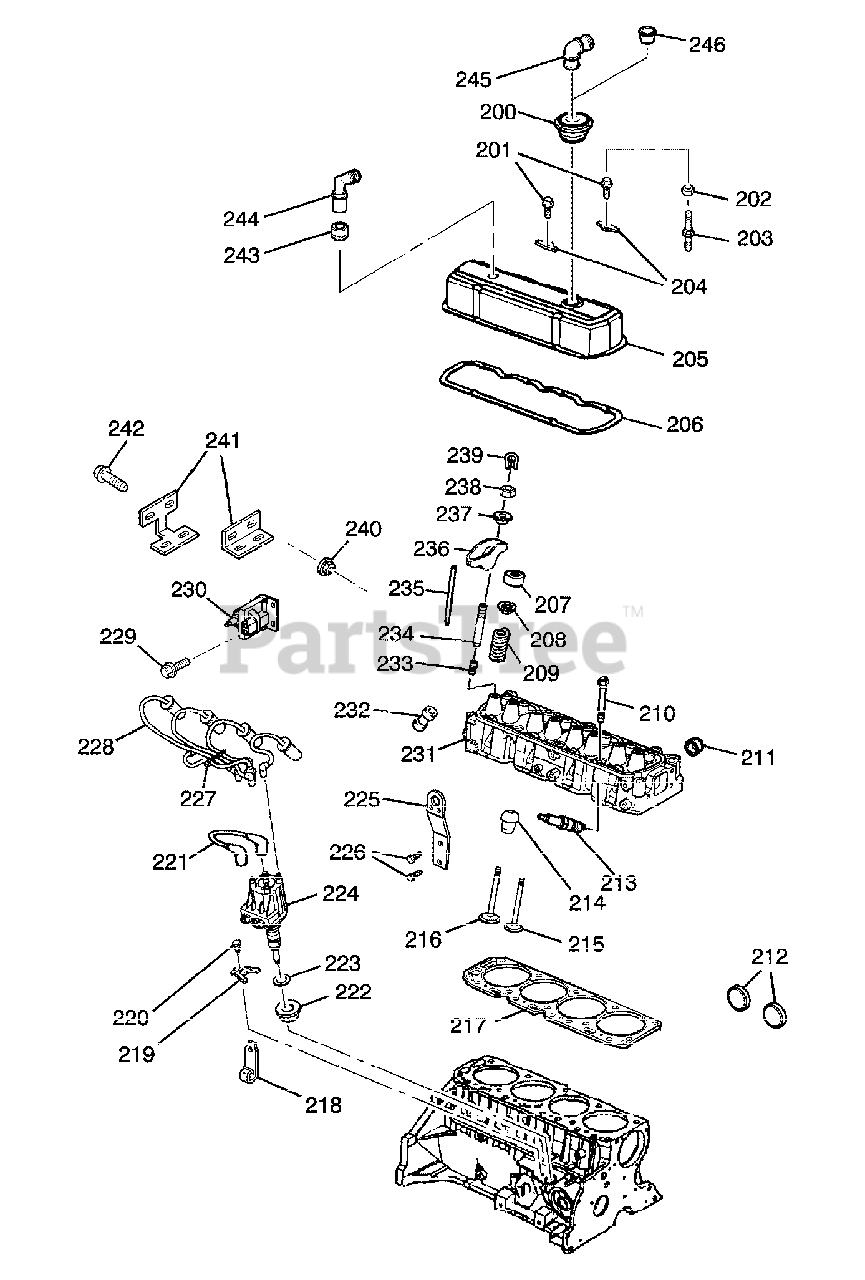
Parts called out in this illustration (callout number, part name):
200	* CAP
201	* BOLT
202	* NUT
203	* STUD
204	* REINFORCEMENT
205	* COVER
207	* SHIELD
208	* CAP
209	* SPRING
210	* BOLT
211	* PLUG
214	* INSERT
215	* EXHAUST VALVE
216	* INTAKE VALVE
218	* CLIP
219	* CLAMP
220	* BOLT
221	HVS COIL WIRE
222	* WASHER
225	* BRACKET
226	* BOLT
227	* RETAINER
229	* BOLT
231	* HEAD
232	* LIFTER
233	* SEAL
234	* STUD
235	* ROD
236	* ARM KIT
237	* BALL
238	* KEY
239	* KEY
240	* PLUG
241	* BRACKET KIT
242	* BOLT
243	* GROMMET
